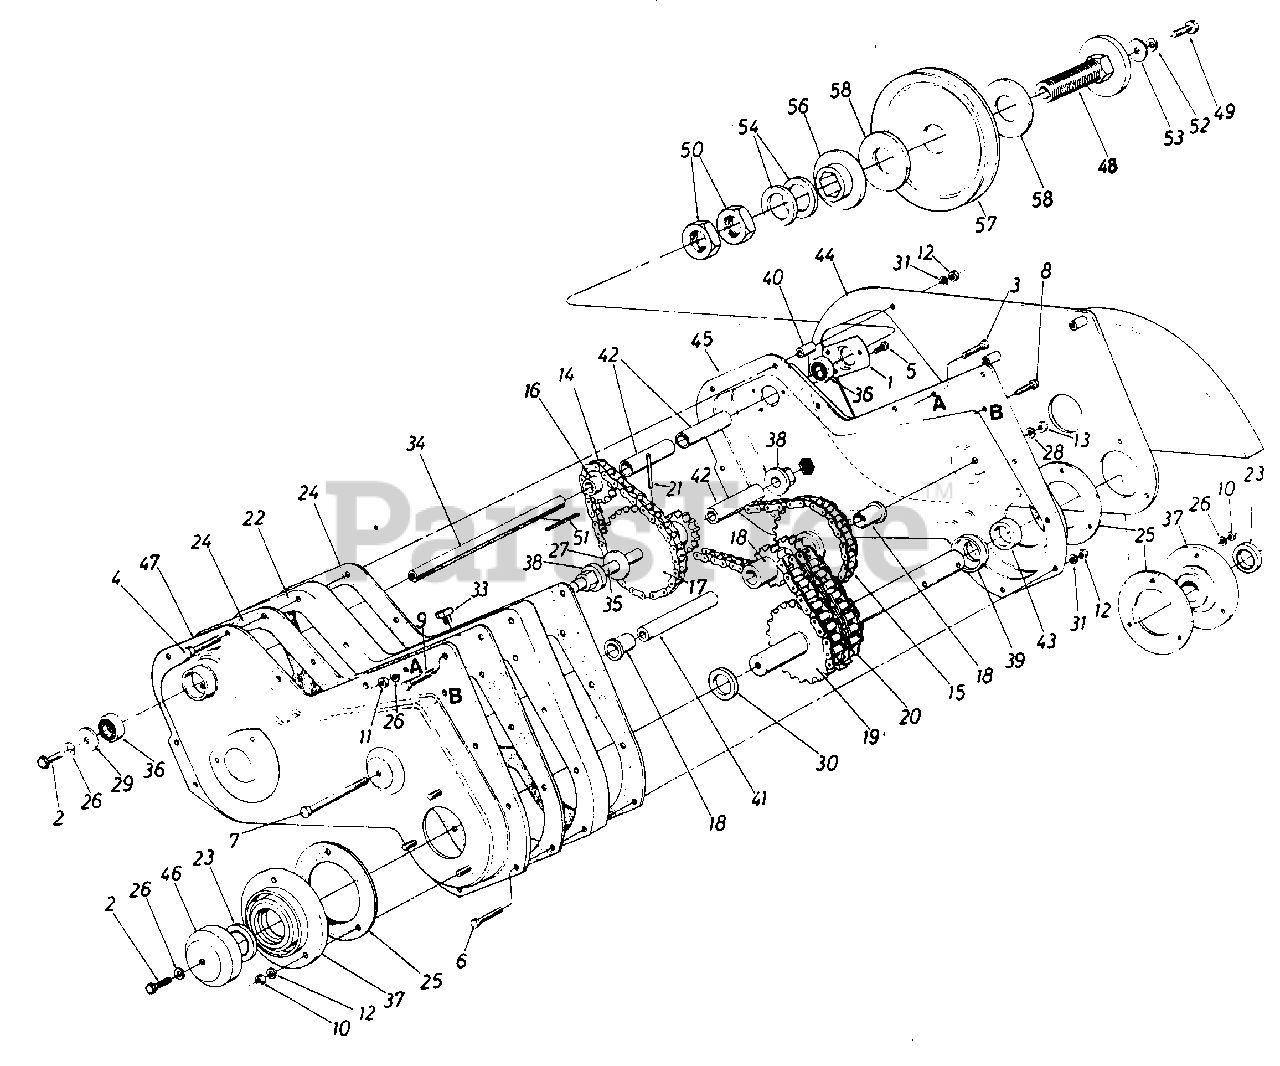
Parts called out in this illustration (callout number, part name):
1	Bearing Housing 1-3/8" Dia.
2	Hex Bolt 5/16-18 x .88" Lg. Spec.
3	Hex Bolt 5/16-18 x 1.50" Lg.*
4	Hex Bolt 1/4-20 x 2.75" Lg.*
5	Hex Wash. S-Tap. Scr. 1/4-20 x
6	Hex Bolt 1/4-20 x 1.50" Lg.*
7	Hex Bolt 3/8-16 x 4.5" Lg.
8	Hex Wash. Hd. Bolt 1/4 20 x 1.5" Lg.
9	Hex Wash. S-Tap Scr. 5/16 18 x 1.75" Lg.
10	Hex Cent. L.-Nut 5/16-18 Thd.
11	Hex Nut 5/16-18 Thd.*
12	Hex Nut 1/4-20 Thd.*
13	Hex Nut 3/8-16 Thd.*
14	#41 Chain 1/2" Pitch x 34 Links-Endless
15	#42 Chain 1/2" Pitch x 48 Links-Endless
16	Sprocket 10 Tooth .500" Pitch
17	10 & 28 Teeth Sprocket Ass'y.
18	18-2 & 28 Sprocket Sleeve Ass'y
19	18-2 Sprocket Shaft Ass'y.
20	#50-2 Chain 5/8" Pitch x 28 Links-Endless
21	Spring Pin Spir. 1/4" Dia. x 1.50" Lg.
22	Spacer Block-Tiller Housing
23	Oil Seal Double Lip 1-1/4" Dia.
24	Gasket for Tiller Housing
25	Gasket for Brg.-Housing
26	L.-Wash. 5/16" I.D.*
27	Fl.-Wash. .640" I.D. x 1.24" O.D.
28	L.-Wash. 3/8" I.D. Heavy Duty
29	Fl. Wash. .344" I.D. x .1.125"
30	Special Washer
31	L.-Wash. 1/4" I.D.*
31	Grease-Plastilube #0
33	Vent Plug
34	Jack Shaft .525" I.D. x 7.78 " Lg.
35	Sprocket Shaft .63" Dia. x 5.0" Lg.
36	Ball Brg. .62" I.D. x 1.38" O.D.
37	Bearing Housing-1-1/4"
38	Hex Flange Brg.
39	Spacer 1.25" I.D. x 2.0" O.D.
40	Spacer.28" I.D. x .62" O.D. x .90" Lg.
41	Spacer.38" I.D. x .62" O.D. x 3.44" Lg.
42	Spacer.62" I.D. x .88" O.D. x 1.56" Lg.
43	Spacer 1.25" I.D. x 1.62" O.D. x.50" Lg.
46	Dust Cap .320" Dia. Hole
49	Hex Bolt 5/16-18 x 1.25" Lg. Grade 5
50	Hex Jam Nut 1.0-14 x 28 Thd.
51	Sq. Key 3/16 x 1.50" Lg.
52	L.-Wash. 5/16" I.D.*
53	Fl.-Wash. .344" I.D. x 1.125" O.D.
54	Spring Bell Wash. 1.0" I.D. x 2.0" O.D.
56	Floating Disc 3-1/4" O.D. x 1.0" I.D.
57	5/8 V-Pulley 1.50" I.D. x 6.50"
58	Friction Pad 3-1/4" O.D. x 1-3/8" I.D.
